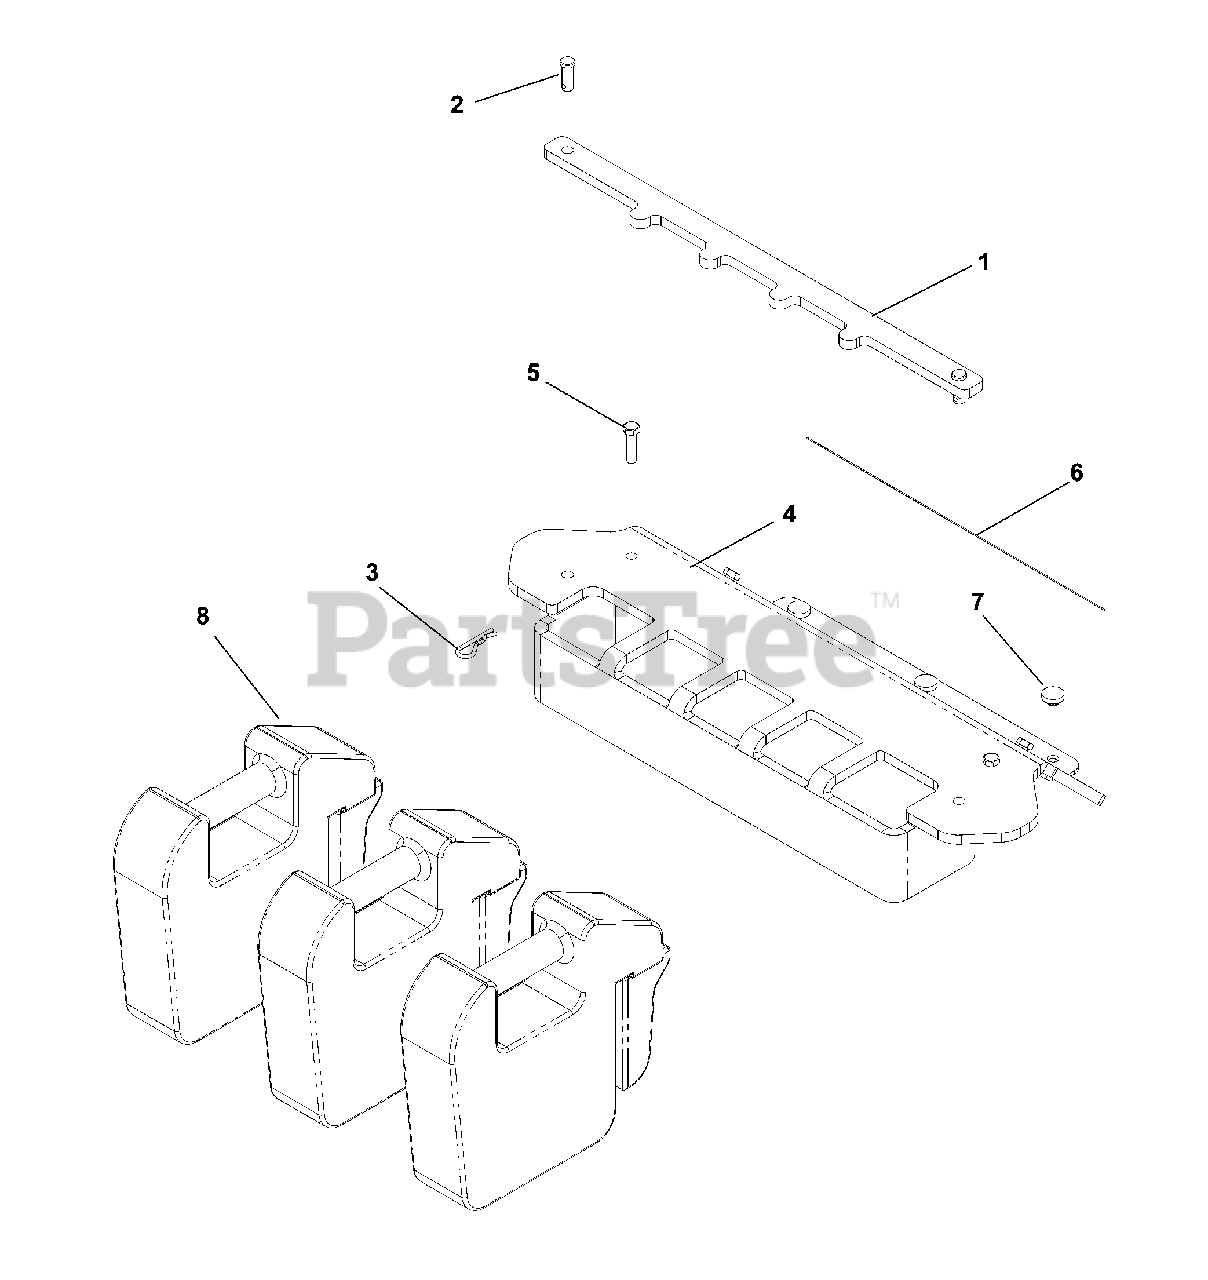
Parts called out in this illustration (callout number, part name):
1	HOLD DOWN, WEIGHT BAR
2	CLEVIS PIN
3	RETAINER SPRING
4	WEIGHT BAR
5	HCS 5/16C X 1 1/4
6	ANTI-SKID PAD
7	GROMMET, BUMPER
8	FRT WEIGHT CAST PZ DFS
